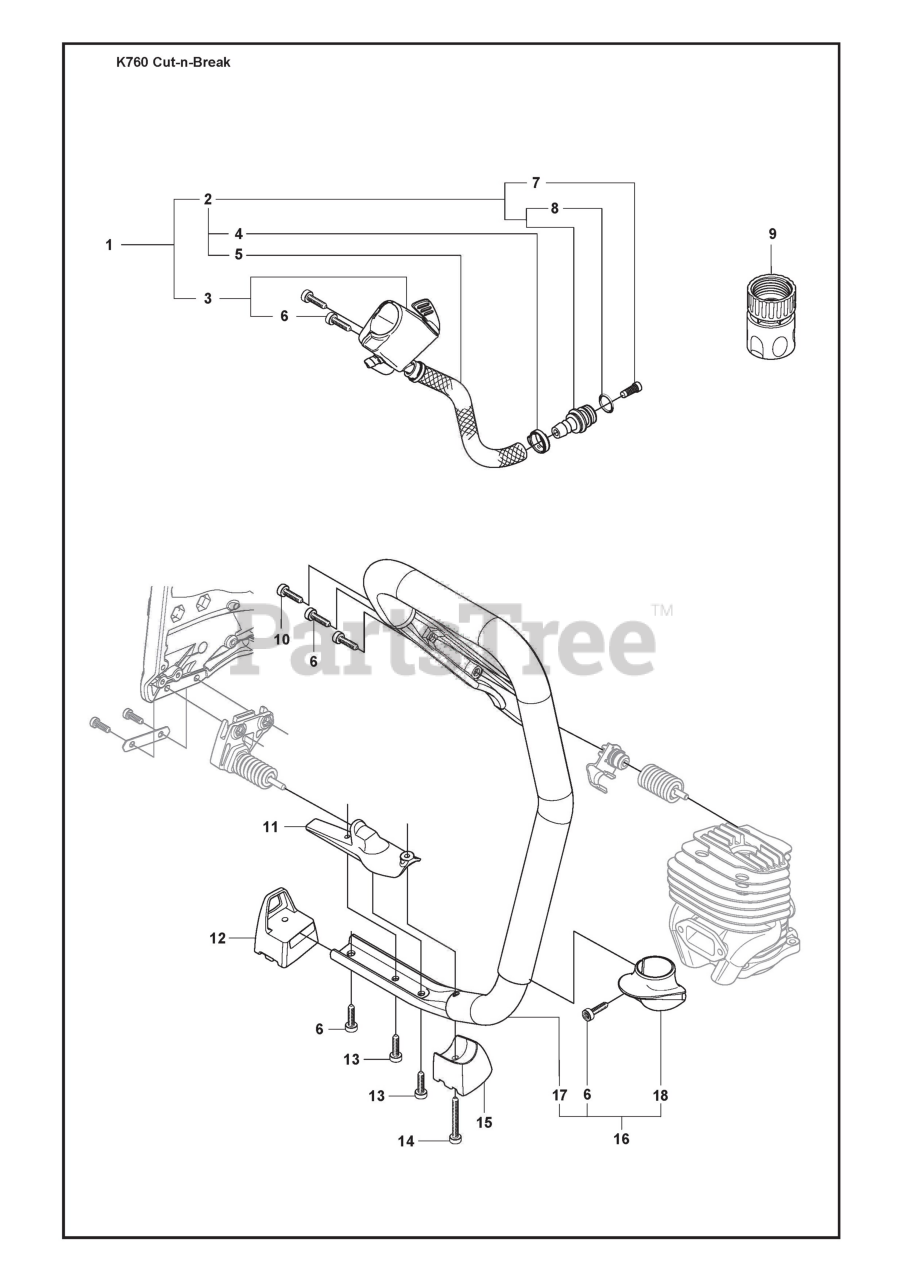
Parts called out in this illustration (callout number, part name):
1	HOSE KIT
2	HOSE ASSY
3	VALVE ASSY
4	HOSE CLAMP
5	HOSE ASSY
9	COUPLING
11	SPRING RETAINER
12	GROUND SUPPORT
15	GROUND SUPPORT
16	HANDLE
17	FRONT HANDLE
